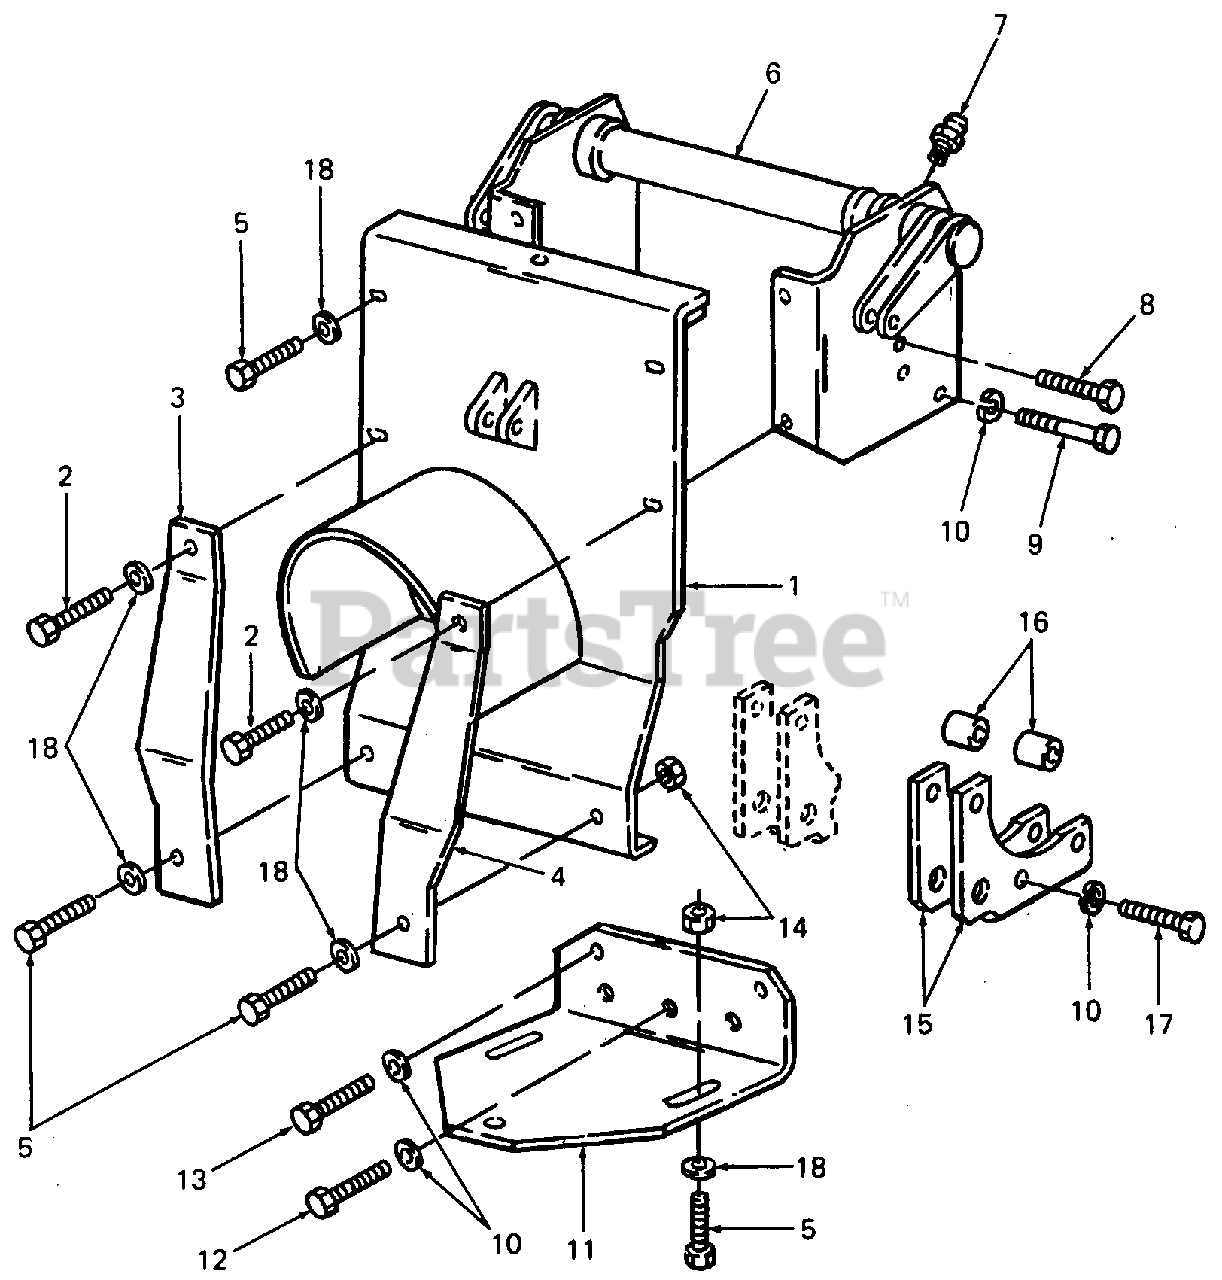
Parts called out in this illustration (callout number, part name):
1	Plate Assy, Drawbar Support
2	Screw, Hex Cap, 3/8-16 X 1.25 Lg GR5
3	Cam, Sway Limiter LH
4	Cam, Sway Limiter RH
5	Screw, Hex Cap, 3/8-16 X 1.00 Lg GR5
6	Rockshaft Assy
7	Fitting, Straight Dr Type Lub
8	Screw, Hex Cap, 3/8-16 X .75 Lg GR8
9	Bolt, Hex Patch, 3/8-16 X 3.25 Lg GR8
10	Washer, Lock, 3/8
11	Tow Plate
12	Bolt, Hex Patch, 3/8-16 X 1.00 Lg GR5
13	Bolt, Hex Patch, 3/8-16 X .75 Lg GR5
14	Nut, Hex Center Lock
15	Plate, Lower Link Support
16	Spacer, Support
17	Bolt, Hex Patch, 3/8-16 X 4.00 Lg GR5
18	Washer, Flat, .406 ID X .810 OD X .051 Thk
